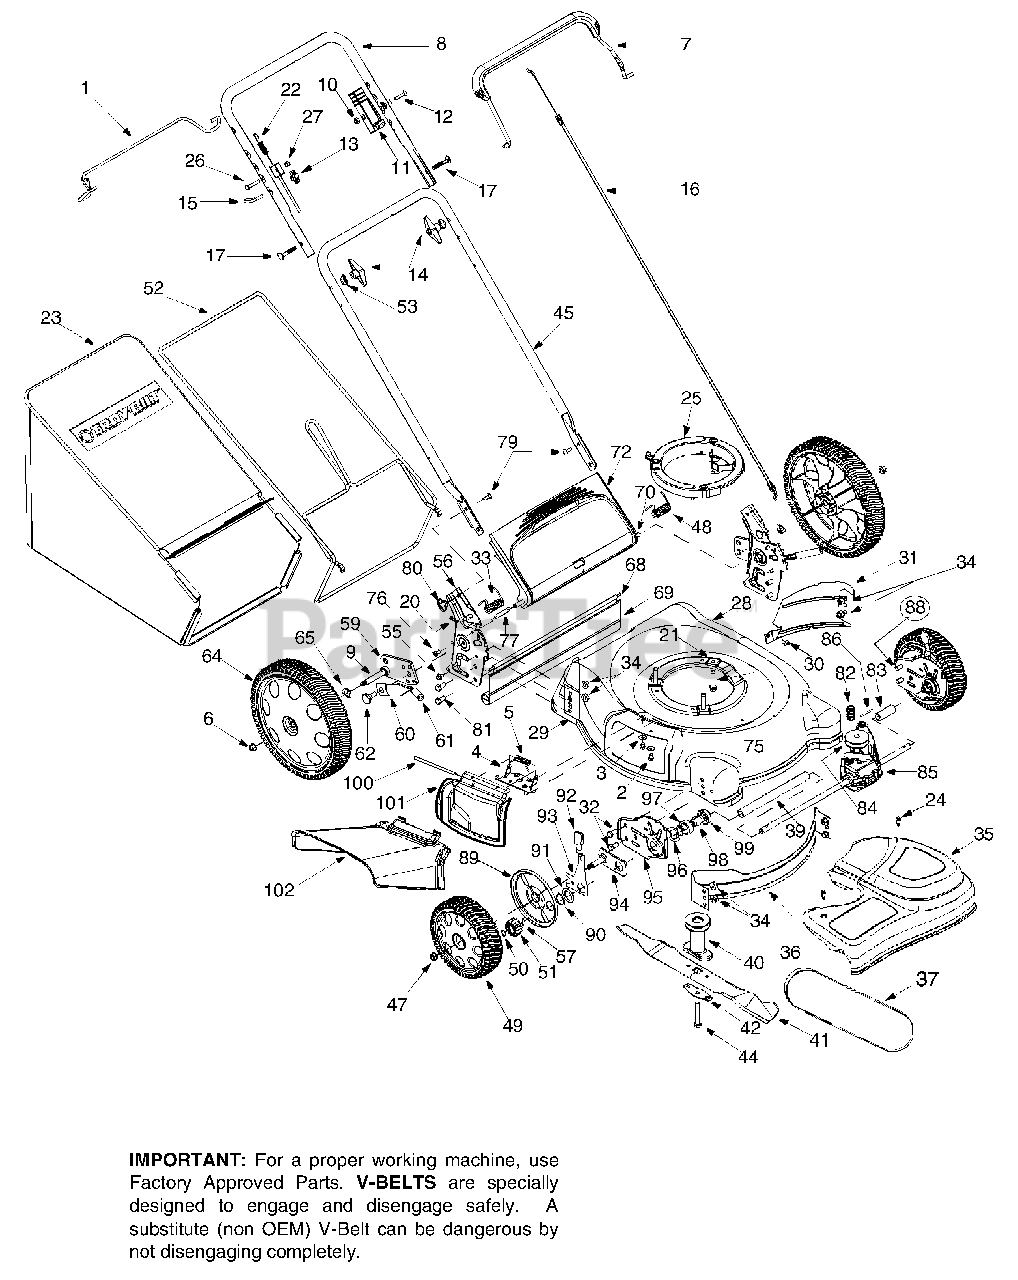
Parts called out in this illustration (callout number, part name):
2	TT Screw 1/4-20 x 0.5
3	Bell Washer .265 x 0.75
5	Torsion Spring
7	Control Lever
10	Hex Lock Nut, 1/4-20
11	Throttle Housing
12	Oval C-Sunk Screw 1/4-20 x 1.31
13	Handle Knob
14	Handle Knob
16	Control Cable: 40.5"
17	Carriage Bolt 5/16-18 x 2.0
18	RH Bracket Assembly
18	LH Bracket Assembly
19	Cable Tie
20	Cotter Pin
21	Self-Tapping Sems Screw
22	Drive Cable
23	Grassbag Assembly
24	Shoulder Screw # 12 -24
25	Engine Spacer
26	Hex Bolt 1/4-20 x 1.5
27	Lock Nut 1/4-20
30	Screw AB: 1/4-14: .625
32	Hex Screw 3/8-16 x .75
33	Torsion Spring
34	Hex Nut 3/8-16
35	Transmission Cover (Black)
38	Hex Nut 1/4-20
39	Sleeve Spacer 10.1" Lg.
40	Blade Adapter w/ Pulley
41	21" Mulching Blade
42	Blade Bell Support
43	Hex Screw 1/4-20 x 1.50
44	Hex Screw 3/8-24 x 2.50
47	Flange Lock Nut
48	Torsion Spring
49	Wheel 8 x 2.125
50	Snap Ring
51	Gear 14T LH FWD
51	Gear 14T RH FWD
53	Saddle Washer
54	Hex Flange Lock Nut 3/8-16
55	Hex Scr. w/Washer 1/4-14 x .625
56	RH Handle Bracket
56	LH Handle Bracket
57	Dowel Pin
58	Pan Head Screw
59	Pivot Bar
60	Height Adj. Lever
61	Foam Grip
62	Shoulder Scr .500 Dia. x .434
63	Washer .401 x .870 x .063
64	Wheel, 14 x 2.125
65	Spring Washer .50 I.D. x 1.0 O.D.
66	Flat Washer
67	Shoulder Screw
68	Wire
69	Rear Trailing Shield
70	Pivot Rod
71	Torsion Spring
72	Rear Discharge Door
75	Shoulder Screw
76	Machine Screw
77	Spacer .375 x .50 x 1.02" Lg.
78	Shoulder Screw 1/4-14
79	Carriage Bolt 1/4-20
80	Wing Nut
81	Hex Bolt 3/8-16 x 1.0"
82	Belt Tension Spring
83	Slev. Spacer 2.1" Lg.
84	Input Pulley
85	Transmission Assembly
88	Height Adjustment Assembly RH
88	Height Adjustment Assembly LH
89	Wheel Dust Cap
90	Snap Ring
92	Adjustment Knob
93	Front Lever RH
93	Front Lever LH
94	Pivot Plate Assembly
97	Bearing Support
98	Bearing Sleeve
99	Bearing Retainer
100	Hinge Pin
101	Mulch Plug Comp.
102	Chute Deflector
